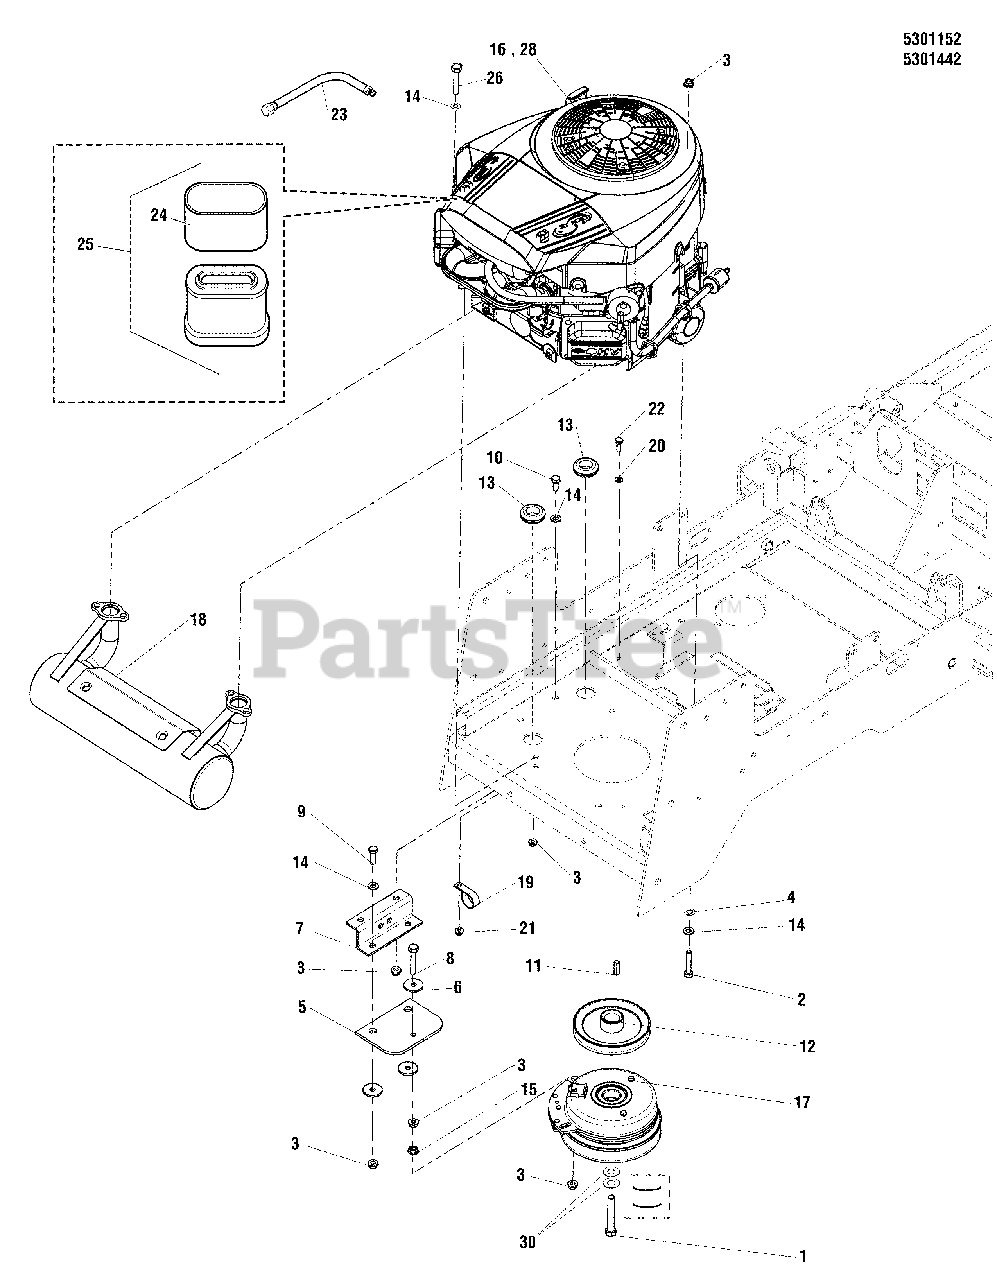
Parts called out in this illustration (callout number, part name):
2	BOLT, 5/16-18 X 1-3/4 GD5 YZ
3	NUT, 5/16-18 HEX NYLOCK FLANGE
4	WASHER, 5/16" INT. TOOTH LOCK
5	CLUTCH ANCHOR PAD
6	WASHER, .34 X 1.25 X 10 GA
7	ANCHOR, CLUTCH - BLK
8	BOLT, 5/16-18 X 2 GD5 TFL
9	BOLT, 5/16-18 X 1 GD5 YZ
10	BOLT, 5/16-18 X 3/4 GD5
11	KEY, 1/4 SQ. X 1.00
12	PULLEY, CRANKSHAFT, 1.0005 ID X 4.95 OD
13	GROMMET, 7/8
14	WASHER, 5/16 SAE
15	NUT, 5/16-18 HEX SERRATED FLANGE (LARGE)
17	CLUTCH, # 5219-34A, ELECTRIC, IS500Z
18	MUFFLER, B&S-ELS
18	MUFFLER, RIGHT OUTLET ASSY
19	CLAMP, VINYL INSULATED
20	WASHER, 1/4 SAE (5025154)
21	NUT, 1/4-20 HEX NYLOCK FLANGE (5025391)
22	BOLT, 1/4-20 X 3/4 GD5 YZ
23	HOSE, OIL DRAIN
24	PRE CLEANER (SV)
25	AIR CLEANER W/ PRE CLEANER (SV)
26	BOLT, 5/16-18 X 1-1/2" GD5 YZ
29	WIRE LOOM, 1/2" PUSH-LOCK, 1.00"
30	BELLEVILLE WASHER 1.1875 X .442 X .089
